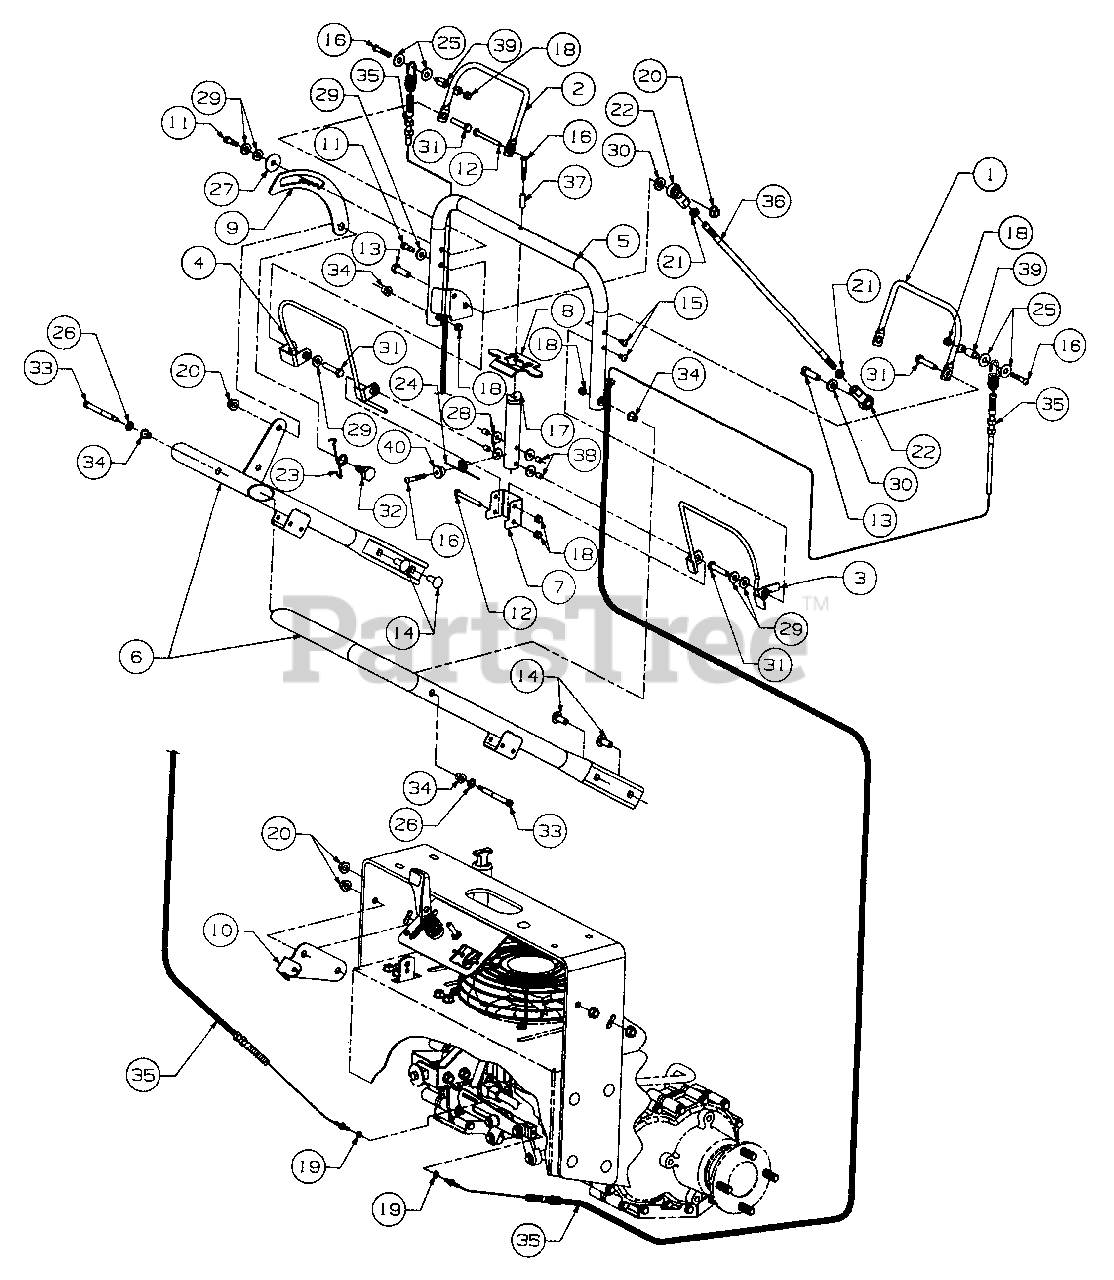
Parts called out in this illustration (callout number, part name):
1	Lever w/Bushings, R.H. Brake
2	Lever w/Bushings, L.H. Brake
3	Lever w/Bushings, Operator-Present
4	Lever w/Bushings & Graphic, Speed Set
5	Bar w/Graphics, Traction Control
8	Latch w/Graphic, Park Brake
9	Plate, Speed Set
10	Bracket, Cable Mounting
11	Screw, Socket Hd Shoulder
12	Screw, Hex Cap, 1/4-20 X 2.50 Lg GR5
13	Screw, Hex Cap, 3/8-16 X 1.25
14	Bolt, Carriage, 3/8-16 X 1.0 Lg GR5
15	Screw, Button Hd, 1/4-20 X .50 Lg
16	Screw, Button Hd, 1/4-20 X 1.50 Lg
17	Post, Parking Brake
18	Nut, Hex Toplock, 1/4-20
19	Nut, Hex, #10-32
20	Nut, Hex Flanged Lock, 3/8-16
21	Nut, Hex Jam, 3/8-24 GR5
22	Rod End, Spherical, 3/8-24
23	Spring, Torsion
24	Spring, Torsion
25	Washer, Flat, .344 X .88 X .063 Thk
26	Washer, Flat, .344 X .62 X .03 Thk
27	Washer, Flat, .32 X 1.25 X .06 Thk
28	Washer, Flat, .281 X .750 X .119 Thk
29	Washer, Flat, .344 X .750 X .120 Thk
30	Washer, Flat, .407 X .8712 X .135 Thk
31	Bolt, Shoulder
32	Bolt, Stepped Shoulder
33	Bolt, Shoulder
34	Bushing, Fliplock
35	Cable, Brake Clutch
36	Rod, F/R Control
37	Spacer, 5/16 OD X 1/4 ID X .94 Lg
38	Spacer, 5/16 OD X 1/4 ID X .375 Lg
39	Spacer, Cable
40	Spacer, Spring Mtg
